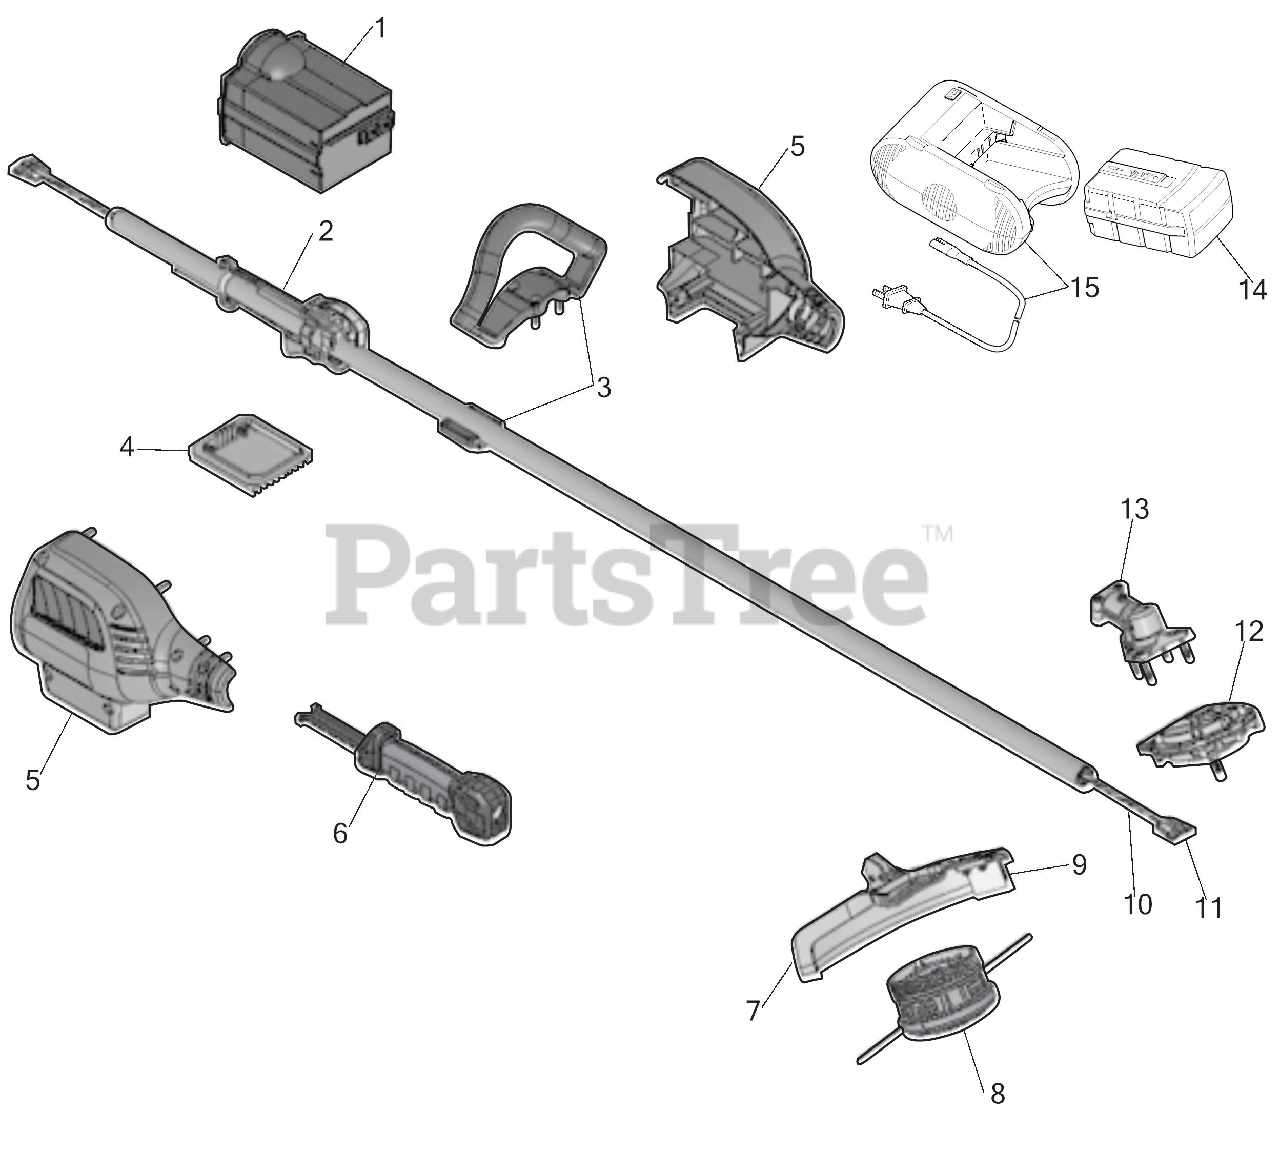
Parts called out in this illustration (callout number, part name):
1	POWER SLEEVE ASSEMBLY
2	BOOM ASSEMBLY W/WIRES CGT400 CORE
3	HANDLE ASSEMBLY CORE
4	CONTROLER CGT400 CORE
5	POWER HOUSING ASSEMBLY
6	ELITE GRIP ASSEMBLY
7	GUARD ASSEMBLY W/BLD CORE
8	BUMPHEAD ASSEMBLY COMP CORE
9	BLADE ASSEMBLY CORE
10	HARNESS PHS WIRE CGT400 CORE
11	HARNESS HALL WIRE CGT400 CORE
12	MOTOR ASSEMBLY CGT400 CORE
13	YOKE ASSEMBLY CGT400 CORE
14	CORE BATTERY 18.5V
15	CHARGER 21V 7AH CRC8000 CORE
